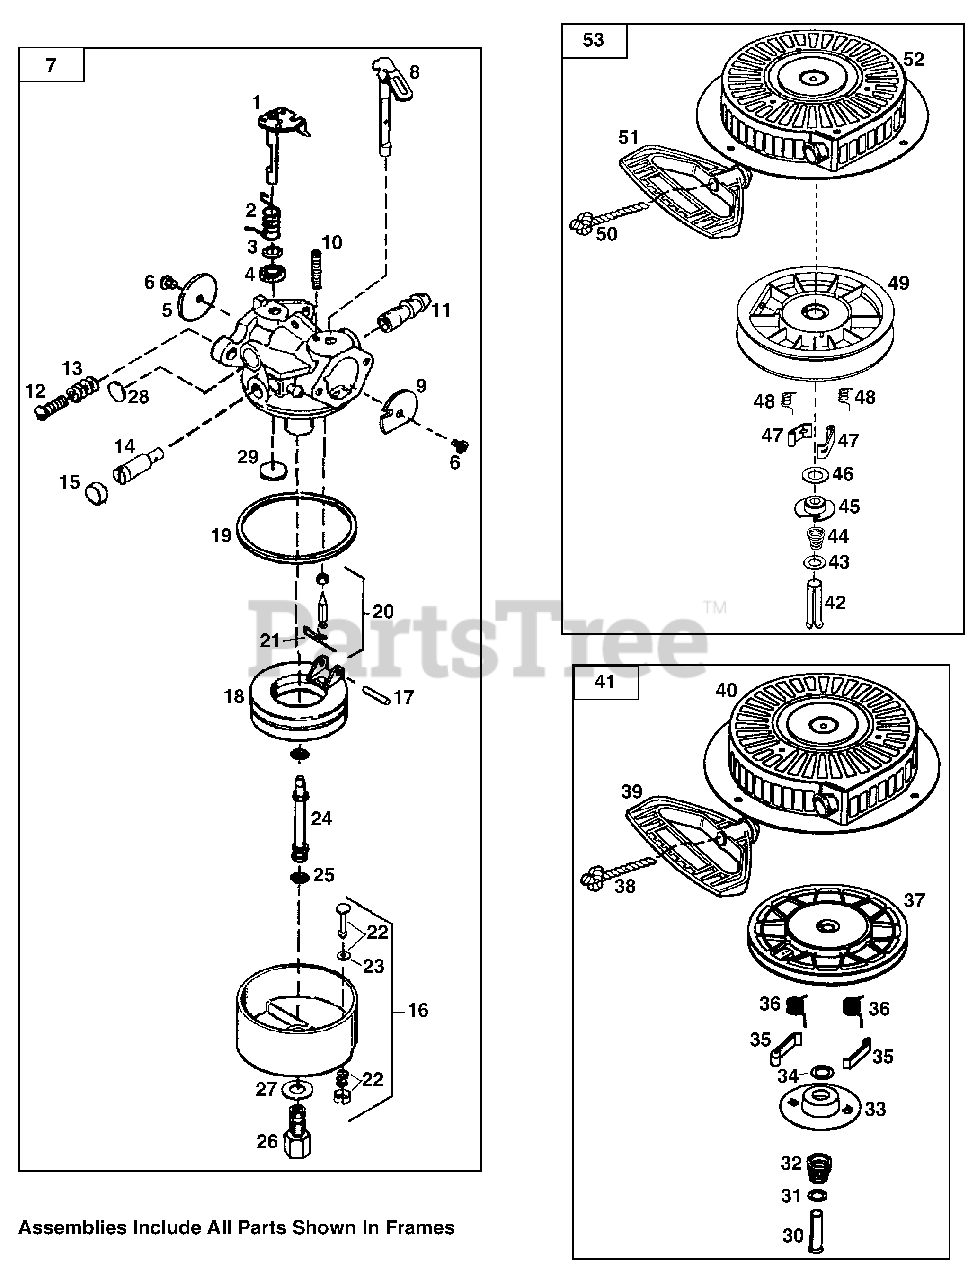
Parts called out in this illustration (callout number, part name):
1	Throttle Shaft & Lever Ass’y
2	Throttle Return Spring
3	Dust Seal Washer
4	Dust Seal (Throttle)
5	Throttle Shutter
6	Shutter Screw
7	Carburetor Ass’y
8	Choke Shaft & Lever Ass’y
9	Choke Shutter
10	Choke Positioning Spring
11	Fuel Fitting
12	Throttle Crack/Idle Speed Screw
13	Tension Spring
14	Idle Restrictor Screw
15	Idle Restrictor Screw Cap
16	Float Bowl
17	Float Shaft
18	Float
19	Float Bowl "O" Ring
20	Inlet Needle, Seat & Clip
21	Spring Clip
22	Bowl Drain Ass’y
23	Drain Plunger Gasket
24	Main Nozzle Tube
25	Main Nozzle Tube "O" Ring
26	High Speed Bowl Nut
27	Bowl Nut Washer
28	Welch Plug, Idle Mixture Well
29	Welch Plug, Atmospheric Vent
30	Spring Pin
32	Brake Spring
35	Starter Dog
36	Dog Spring
37	Pulley & Rewind Spring Ass’y
38	Starter Rope (98")
39	Mitten Grip Starter Handle
40	Starter Housing Ass’y
41	Rewind Starter Ass’y
42	Spring Pin
44	Brake Spring
47	Starter Dog
48	Dog Spring
49	Pulley & Rewind Spring Ass’y
50	Starter Rope (98")
51	Mitten Grip Starter Handle
52	Starter Housing Ass’y
53	Rewind Starter Ass’y
